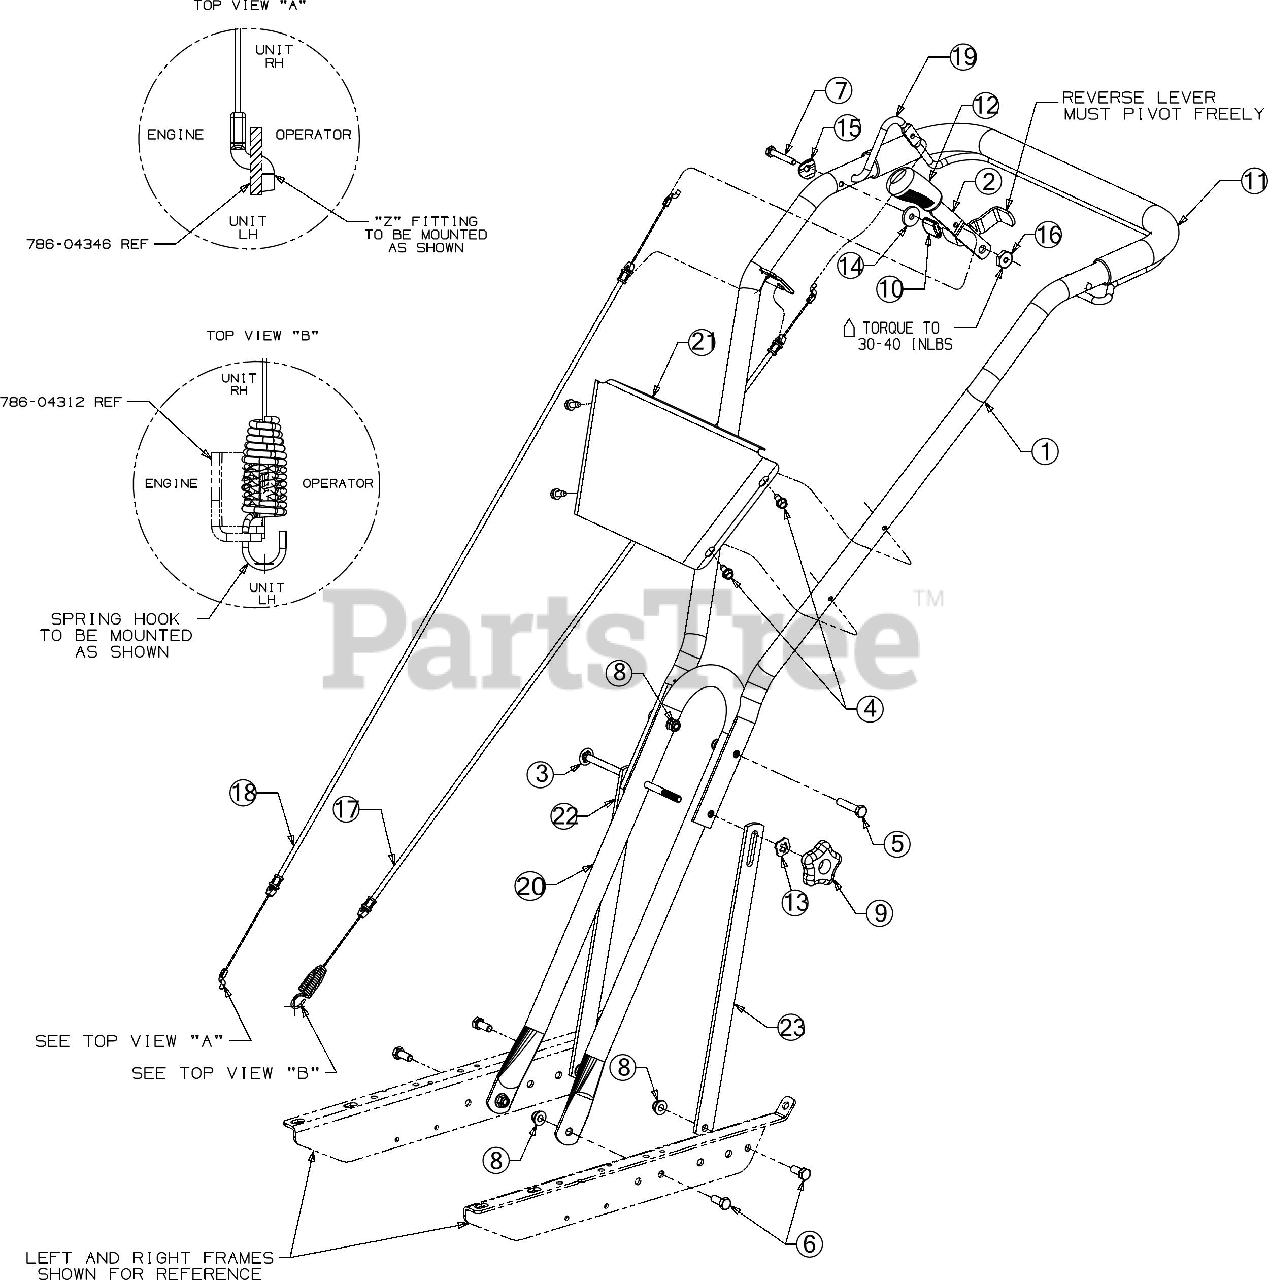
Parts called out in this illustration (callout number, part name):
1	UPPER HANDLE ASSEMBLY
2	REVERSE HANDLE ASSEMBLY
3	SCREW 5/16-18 x 6.75
4	SCREW 1/4-20 X.500
5	SCREW 5/16-18 x 1.5 LG
6	SCREW 5/16-18 x .75 GR5
7	BOLT 1/4-20X1.62 GR5
8	FLANGE LOCK NUT 5/16-18
9	STAR KNOB 5/16-18
11	HANDLE GRIP
12	BRAKE HANDLE GRIP
13	SPECIAL WASHER
14	FLAT WASHER
15	SADDLE WASHER
16	SHOULDER SPACER
17	FORWARD CABLE
18	REVERSE CABLE
23	SUPPORT BRACKET
